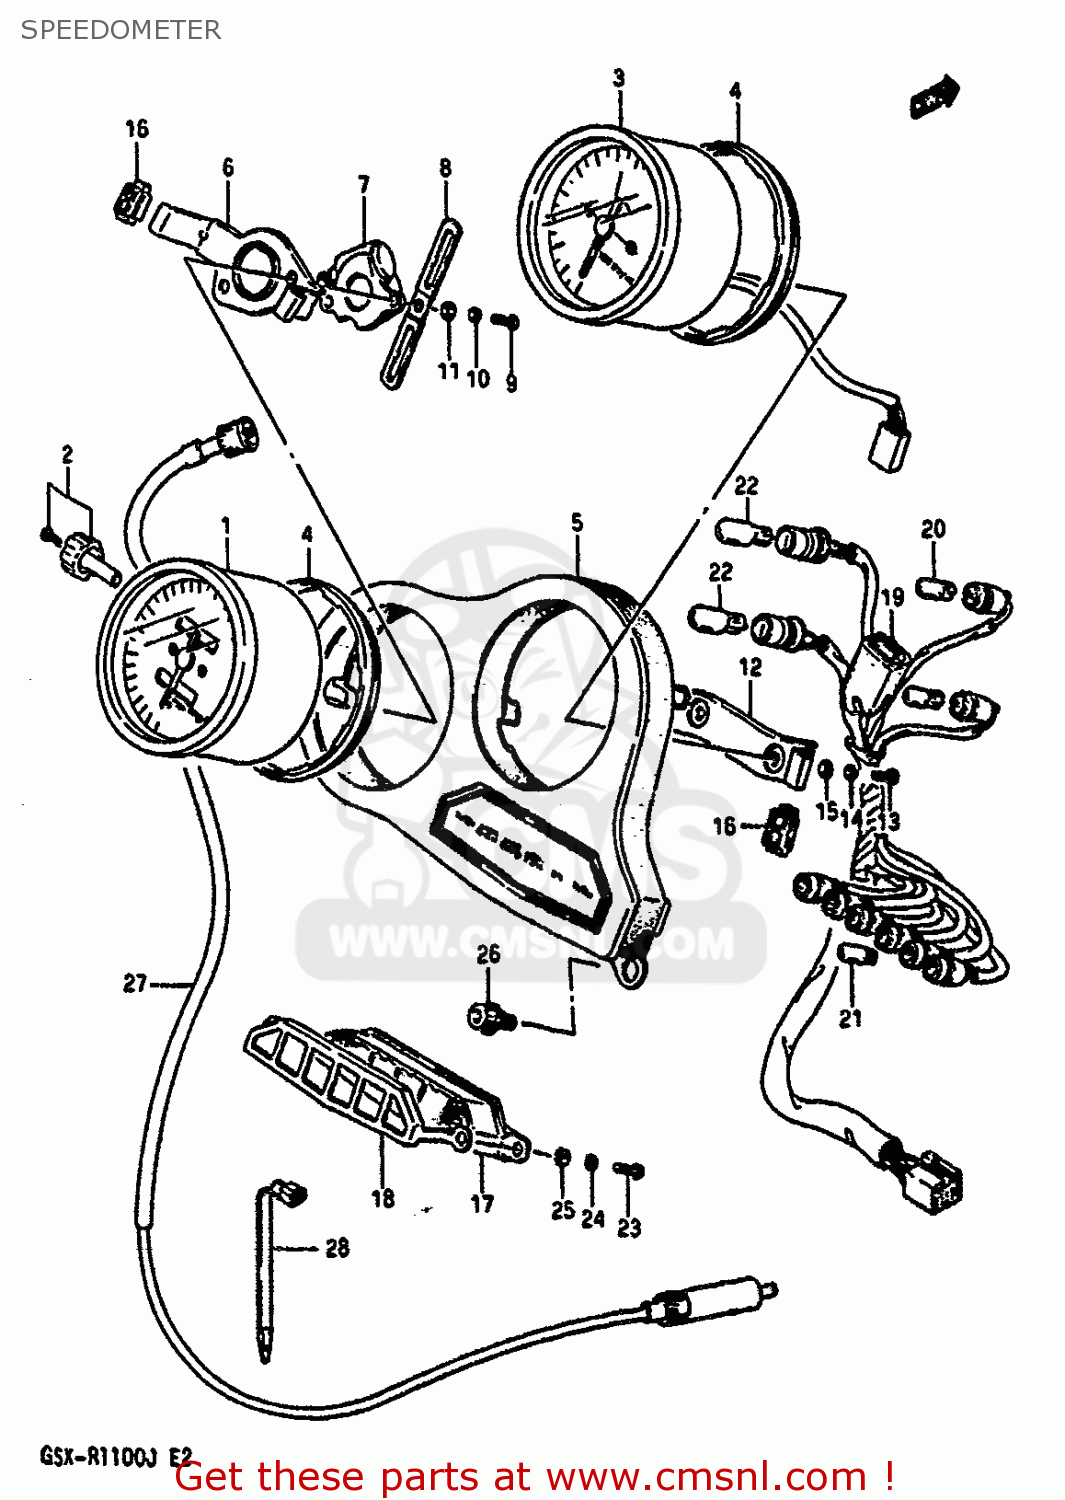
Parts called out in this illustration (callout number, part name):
1	SPEEDOMETER (KILO)
2	KNOB,TRIP
3	TACHOMETER
4	CUSHION
5	BRACKET,METER
6	PLATE,SPEEDOMETER
7	BOX,GEAR
8	CLAMP
9	SCREW
10	LOCK WASHER
11	WASHER
12	PLATE,TACHOMETER
13	SCREW
14	LOCK WASHER
15	WASHER
16	CUSHION
17	BOX,PILOT LAMP
18	PLATE,PILOT LAMP
19	SOCKET,METER
20	BULB(12V3W,T6.5)
21	BULB(12V1.7W,T6.5)
22	BULB(12V3.4W,T10)
23	SCREW
24	LOCK WASHER
25	WASHER
26	BOLT
27	CABLE ASSY,SPEEDOMETER
28	CLAMP(L:125)
